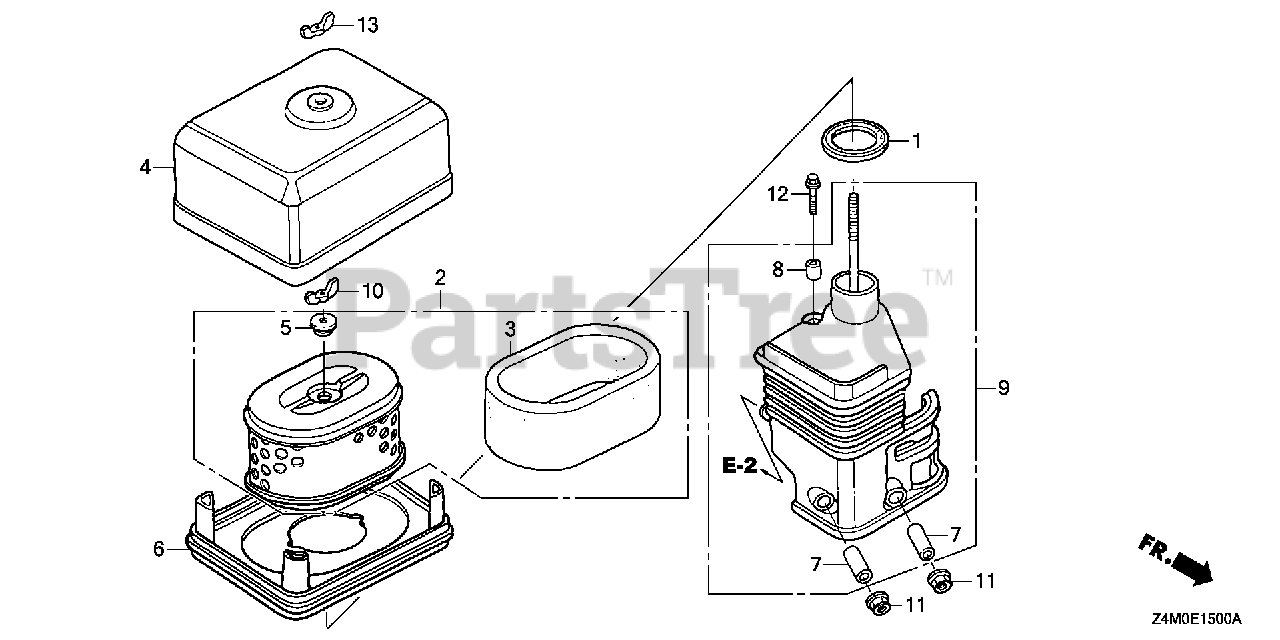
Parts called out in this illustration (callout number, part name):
1	GASKET, ELBOW
2	ELEMENT, AIR CLEANER (DUAL)
3	FILTER (OUTER)
4	COVER, AIR CLEANER
5	GROMMET, AIR CLEANER
6	NOSE, MUFFLER
7	COLLAR, AIR CLEANER
8	COLLAR B, AIR CLEANER
9	ELBOW, AIR CLEANER
10	NUT, TOOL BOX SETTING
11	NUT, FLANGE (6MM)
12	BOLT, FLANGE (6X20)
13	NUT, AIR CLEANER
